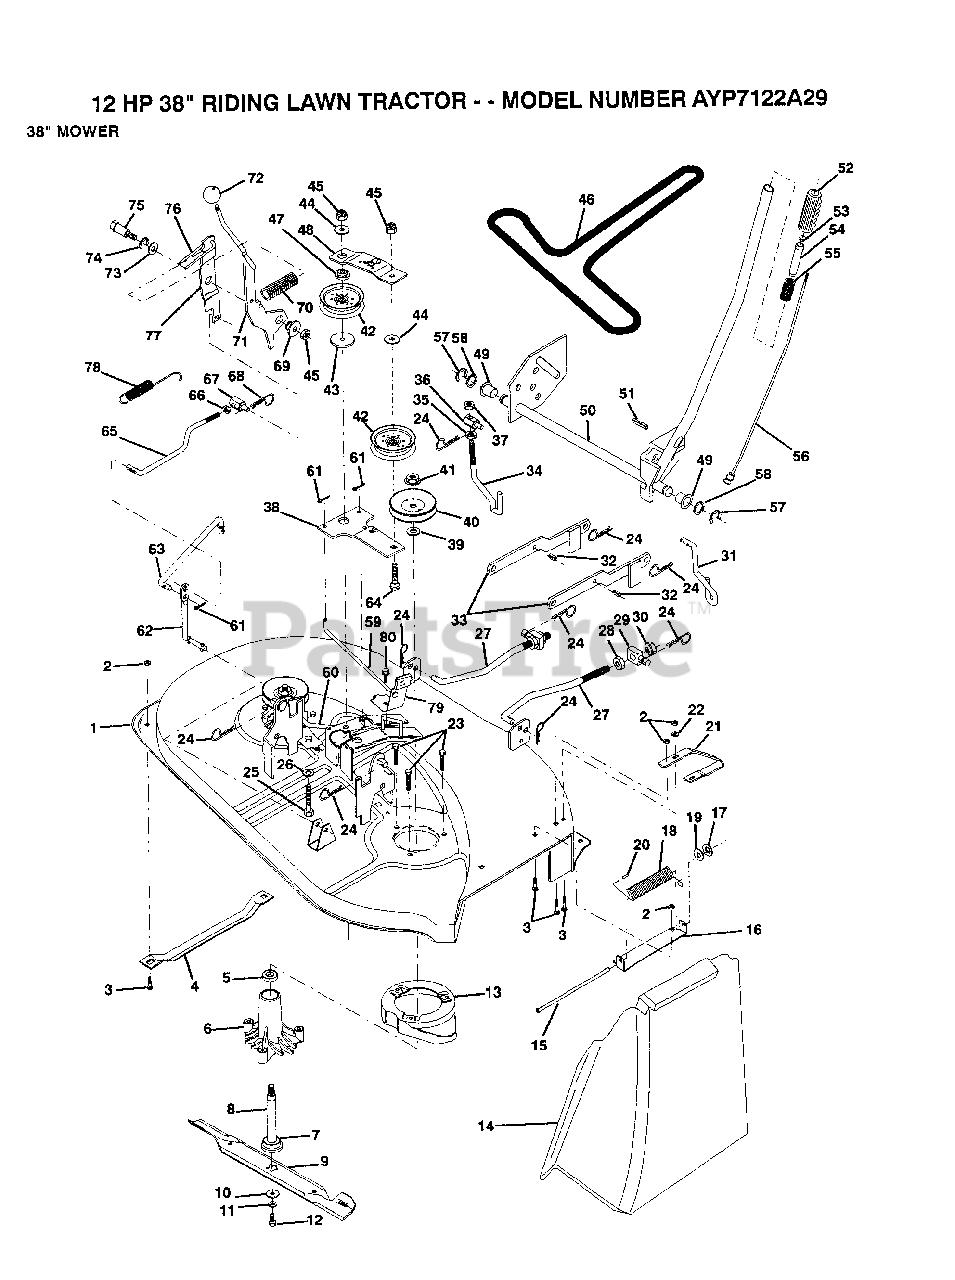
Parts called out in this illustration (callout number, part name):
3	BOLT
4	RUNNER-LH M
5	BEARING
6	HSG ASM MANDREL
7	BEARING.BALL
10	WASHER BLADE
12	BLADE BOLT
14	DEFLECTOR-SHLD T
15	ROD-HINGE T
17	NUT PUSH M
19	WASHER
20	CAP-SLEEVE LT
21	RUNNER RH
22	WASHER M
25	BOLT
26	WASHER GT
27	LINK.FRONT
28	NUT
29	TRUNION
30	NUT LTV
31	LINK LIFT RH
32	SPRING PIN
34	LIFT LINK LH
35	NUT
38	IDLER ARM ASSY
39	WASHER
42	FLAT IDLER PULLEY
43	SPACER RETAINER
44	WASHER GT
46	BELT-V.88.12.MW
47	RETAINER SPACER
48	IDLER ARM STIFF
49	NYLON BEARING
51	PIN-GROOVE LT
52	GRIP
58	WASHER
59	BRAKE ROD RH
60	BRAKE ROD LH
62	PIVOT ROD
63	CLUTCH ROD SECOND
64	BOLT
66	NUT
67	TRUNION
68	RETAINER M
69	BUSHING
72	KNOB T(3/8 HOLE)
73	WASHER
74	RING
75	SHOULDER BOLT
76	SPRING KEEPER
77	CLUTCH ARM SECOND
78	RETURN SPRING
79	BRAKE ASM
80	SCREW
